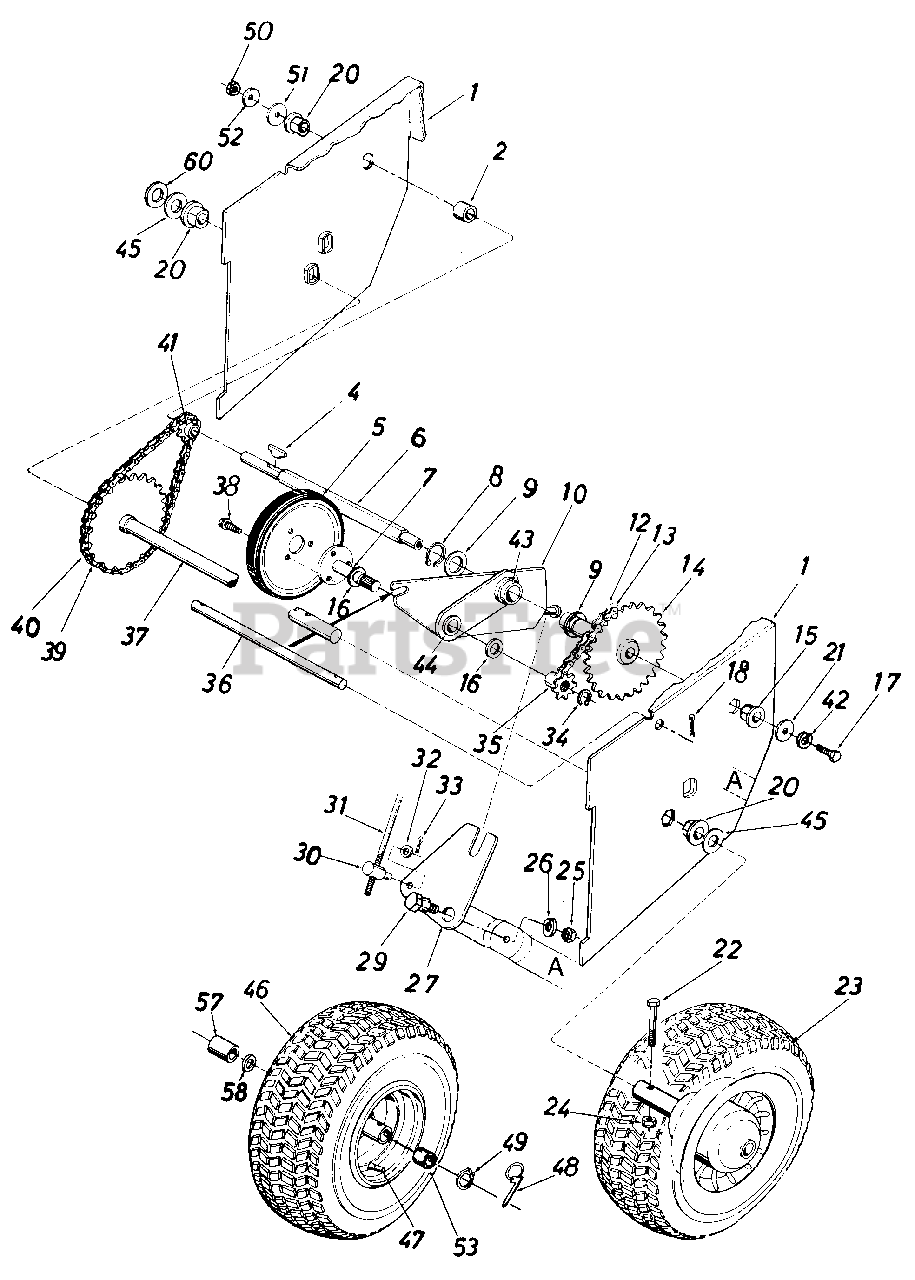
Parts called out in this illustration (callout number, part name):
1	Frame Ass'y.
2	Hex Shaft
4	#4 Hi-Pro Key 3/32 x 518" Dia.
5	Friction Wheel Ass'y.
6	Flange Brg. w/Flats .75" I.D.
7	Friction Wheel Mounting Plate Ass'y.
8	Snap Ring 1.00" Dia. Shaft
9	Fl-Wash. 1.00 x 1.63" O.D. x .03
10	Sliding Bracket Ass'y.
12	#41 Chain 1/2" Pitch x 35 Links
13	Master Link for #41 Chain
14	32 Teeth Sprocket Ass'y.
15	Hex Flange Brg. .630" I.D.
16	Fl-Wash. .62" I.D. x 1.00" O.D. x .06
17	Hex Lock Bolt 5/16-18 x .62" Lg
18	Cotter Pin 3/32" Dia. x .75" Lg.
20	Flange Brg. w/Flats .75" I.D.
21	Fl-Wash. .34" I.D. x 1.12" O.D. x .125
22	Hex Bolt 5/16-24 x 1.50" Lg. (420)
23	Wheel Ass'y.
24	Hex Ins. Jam L-Nut 5/16-24 Thd. (420)
25	Hex Jam Nut 3/8-16 Thd.
26	L-Wash. 3/8" I.D.
27	Shifting Linkage Bracket
29	Shld. Bolt .625" Dia. x .170" Lg.
30	Adjustment Ferrule
31	Shifting Rod 5/16" Dia. x 32.50" Lg.
32	Fl-Wash. .34" I.D. x .64" O.D. x .06
33	Cotter Pin 3/32" Dia. x .75" Lg.
34	Snap Ring .562" Dia. Shaft
35	Sprocket 7 Teeth x .50" Pitch
36	Shaft .50" Dia. x 9.50" Lg.
37	28 Teeth Wheel Axle Ass'y. (420)
38	Hex Wash. Hd. Self-Tap Scr. 5/16-24 x .50" Lg.
39	#41 Chain 1/2" Pitch x 43 Links (420)
40	Master Link for #41 Chain (420)
41	8 Teeth Center Sprocket
42	L-Wash. 5/16" I.D.
43	Bearing
44	Bronze Bearing
45	Fl-Wash. .76" I.D. x 1.49 O.D.
46	Wheel
46	Wheel Ass'y. Comp. (524) 13 x 5.0
47	Air Valve
48	Klick Pin (524)
49	Snap Ring .75 Dia. (524)
50	Hex Ins. L-Nut 1/2-20 Thd.
51	Fl-Wash. .53 I.D. x 1.25 O.D. x .10
52	Bell-Wash. .50 I.D. x 1.0 O.D. x .075
53	Sleeve Brg. (524)
